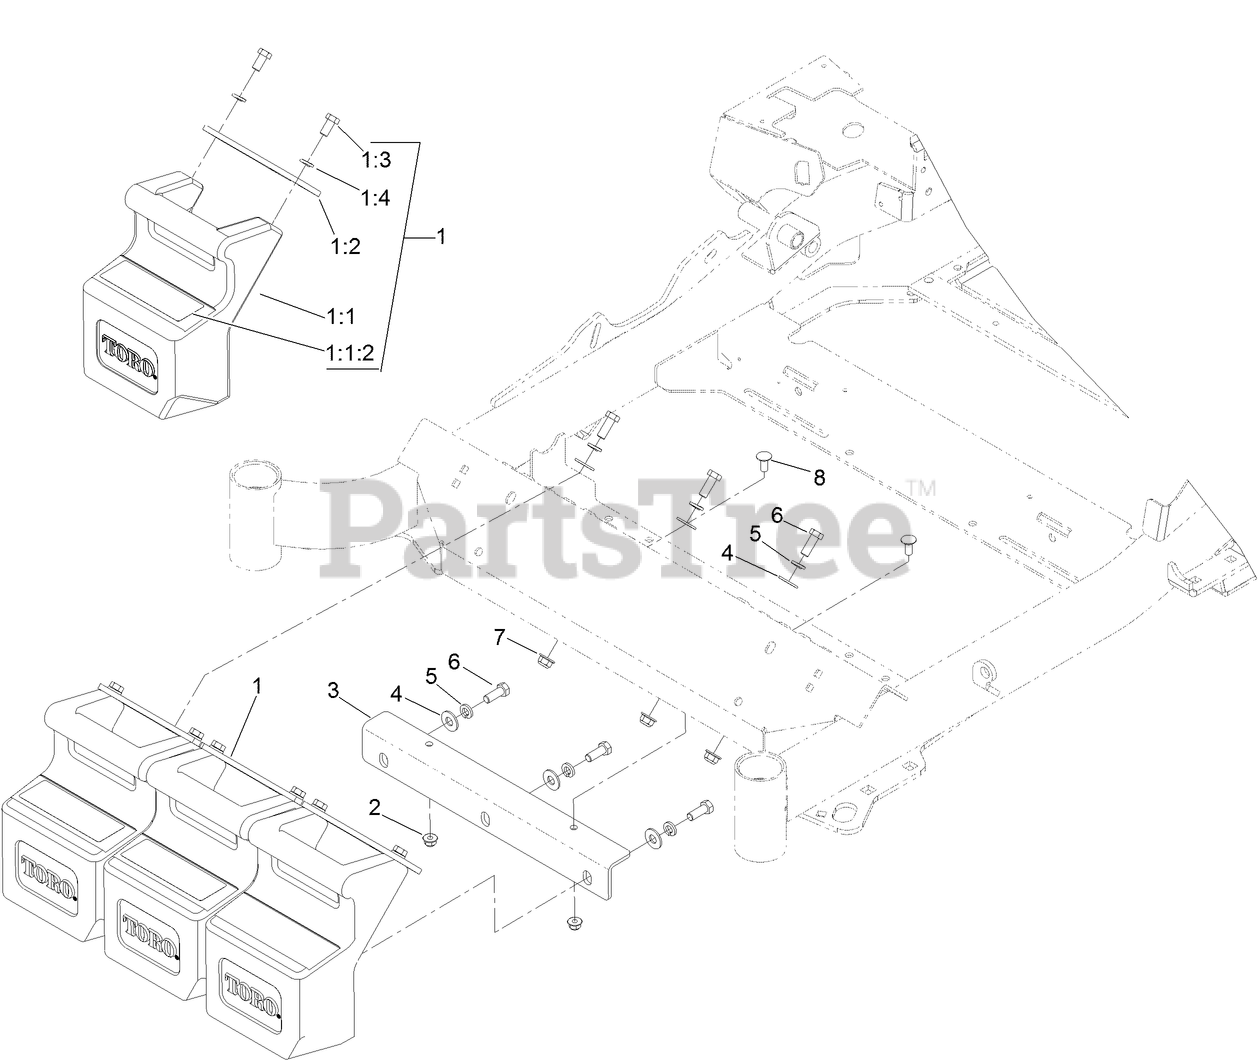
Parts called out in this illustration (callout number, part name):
1	WEIGHT ASM
1:1	WEIGHT
1:1:2	Decal-Warning, Counterweight
1:2	TAB-SUPPORT, WEIGHT
1:3	SCREW-HH
1:4	WASHER-LOCK
2	NUT-HF, NI
3	BRACKET-MOUNT, WEIGHT
4	WASHER-FLAT
5	WASHER-LOCK
6	SCREW-HH
7	NUT-HF, NI
8	SCREW-CARR
